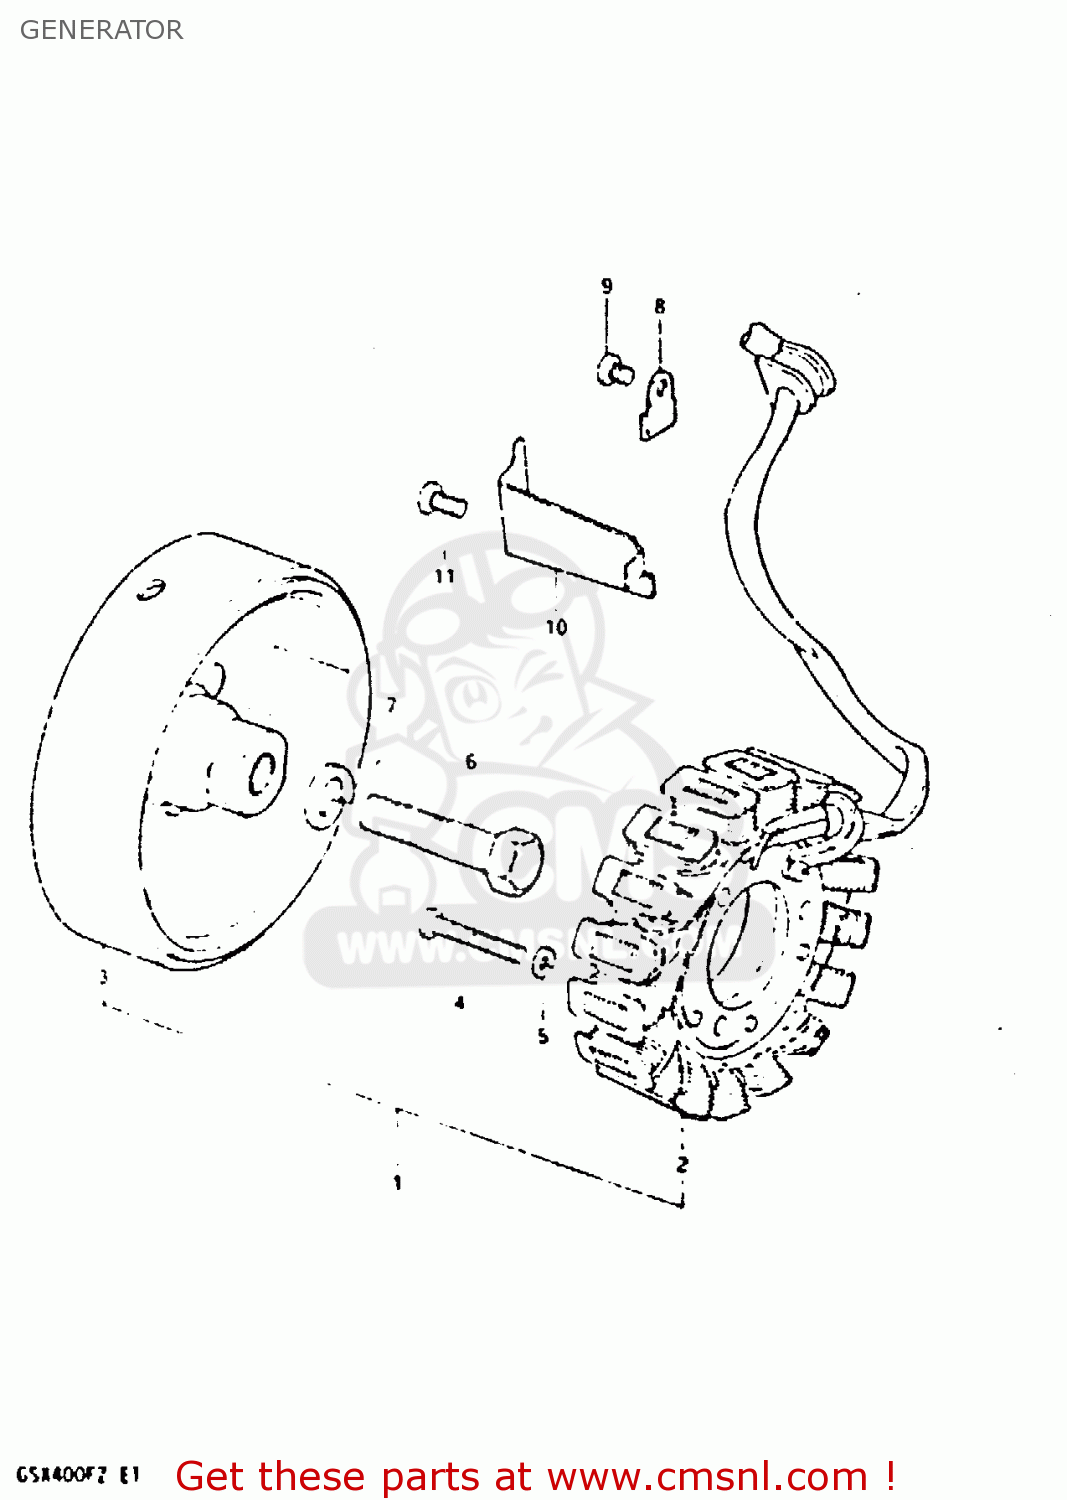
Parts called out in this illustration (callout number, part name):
1	GENERATOR ASSY
2	STARTOR
3	ROTOR ASSEMBLY
4	SCREW
5	LOCK WASHER
6	BOLT 12X45
7	WASHER,LOCK 12
8	CLAMP,GENERATOR LEAD WIRE
9	SCREW
10	CLAMP,GENERATOR LEAD WIRE
11	SCREW
